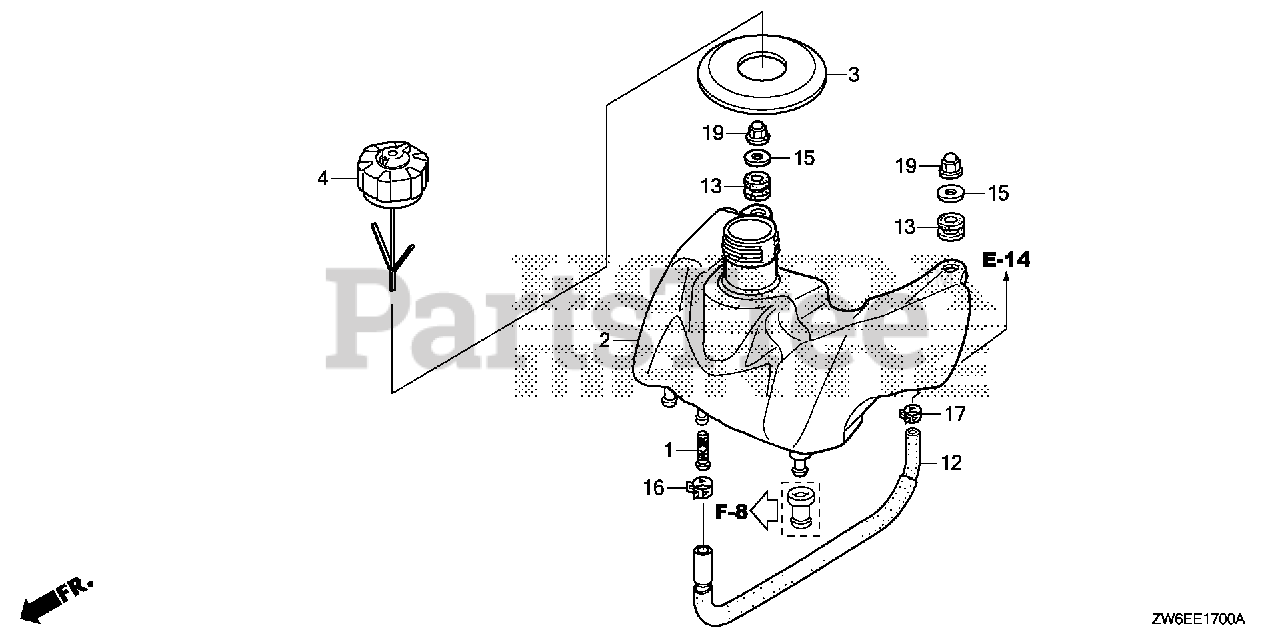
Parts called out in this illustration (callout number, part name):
1	FILTER, FUEL
2	TANK, FUEL (FOR U.S.A.)
3	RUBBER, TANK CAP
4	CAP ASSY., FUEL TANK
5	INNER, FUEL CAP (NOT AVAILABLE)
6	SPONGE, FUEL CAP BREATHER
7	GASKET, FUEL CAP
8	VALVE, BREATHER
9	SPRING, FUEL CAP
10	GASKET, BREATHER VALVE (NOT AVAILABLE)
11	TETHER, FUEL CAP
12	TUBE, FUEL
13	CUSHION, AIR CLEANER
15	WASHER, PLAIN (6MM)
16	CLAMP, TUBE (D10.5)
17	CLAMP, TUBE (8.0)
18	PIN, LOCK (6MM)
19	NUT, CAP (6MM)
